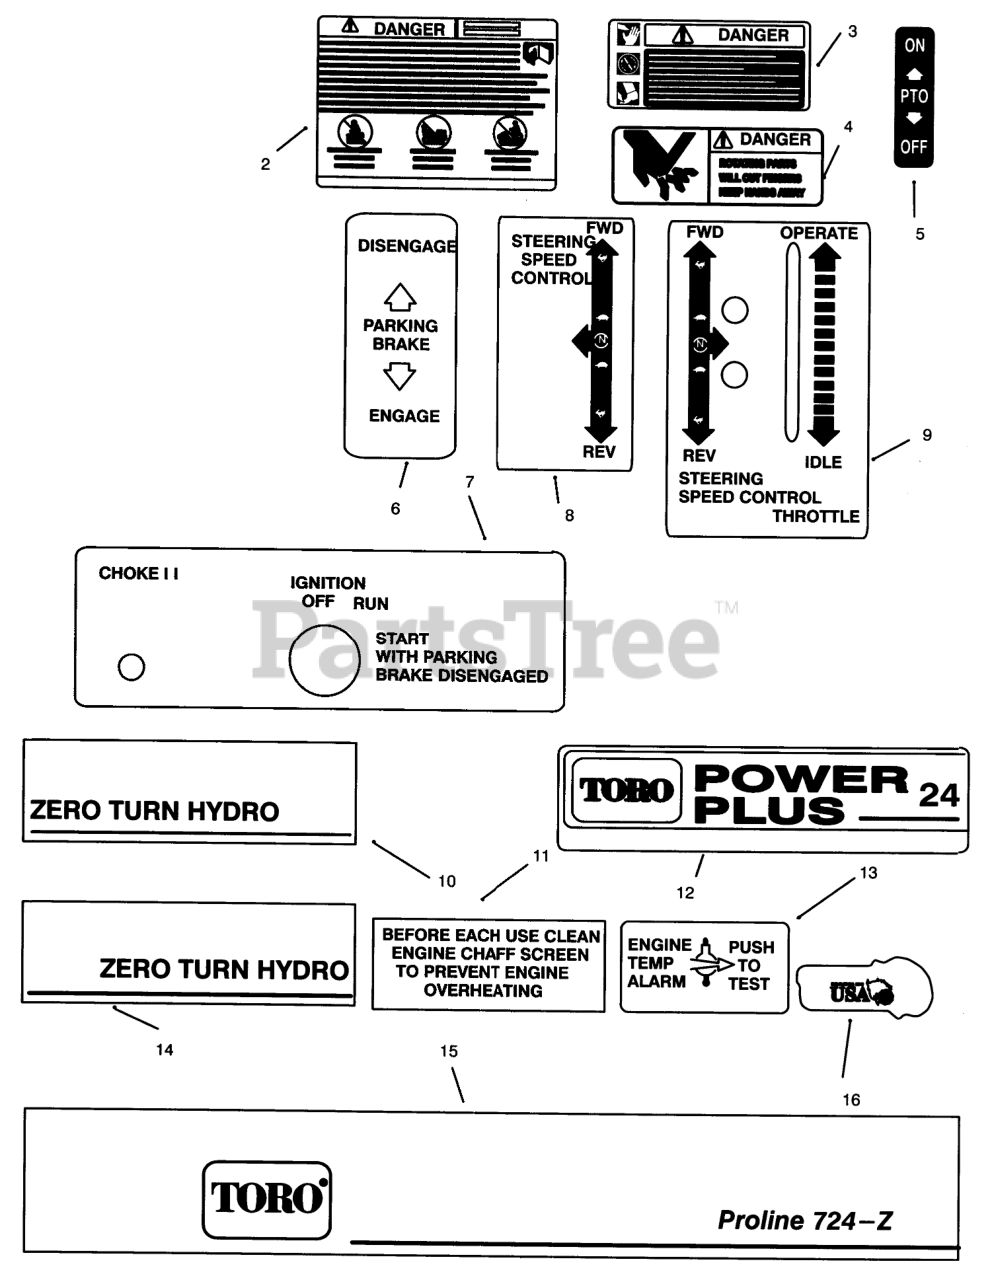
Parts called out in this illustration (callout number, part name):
2	DECAL-DANGER
3	DECAL-DANGER
4	DECAL - DANGER
5	DECAL-PTO
6	DECAL-PARKING BRAKE
7	DECAL-CHOKE/IGNITION
8	DECAL-STRG SPEED CNT
9	DECAL THROTTLE
10	DECAL-ZERO TURN R.H.
11	DECAL-ENGINE SCREEN
12	DECAL-PWR PLUS 24 PL
13	DECAL-TEMP ALARM
14	DECAL-ZERO TURN L.H.
15	DECAL-TORO 724-Z
16	DECAL-MADE IN USA BK
